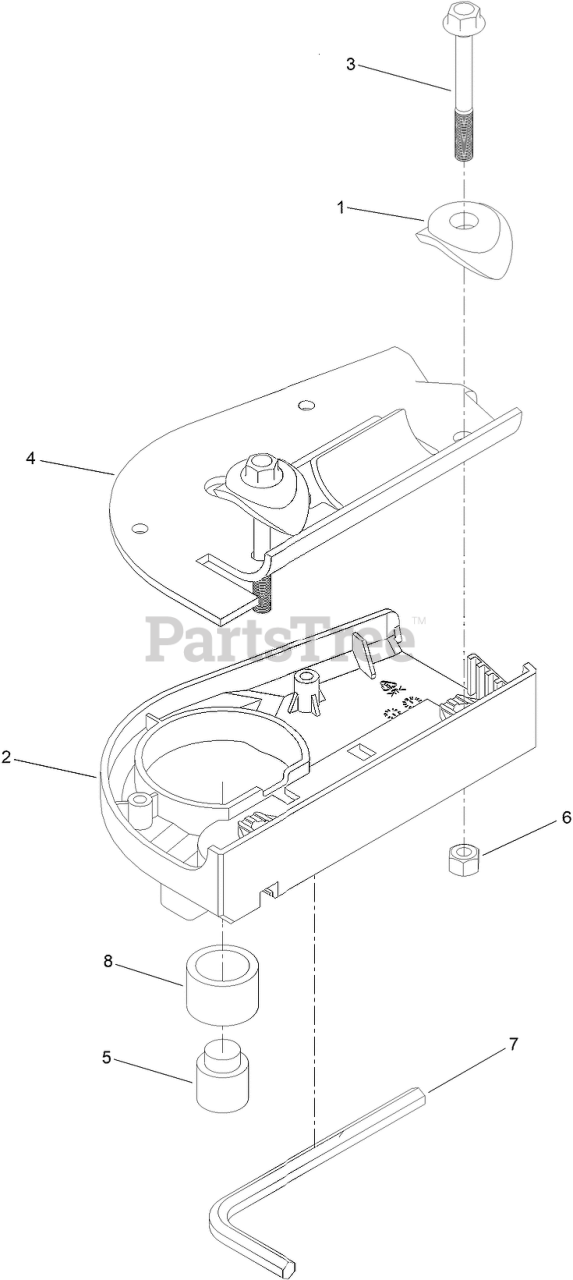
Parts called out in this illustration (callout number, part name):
1	WASHER-CURVE
2	CASING - LEVER
3	BOLT-FLANGE, HEX
4	PLATE-BRACKET, LEVER RAISE TINE
5	BOSS-PLATE, BRACKET LEVER
6	NUT-HEX
7	KEY- ALLEN, HEX
8	BOSS-PLASTIC
